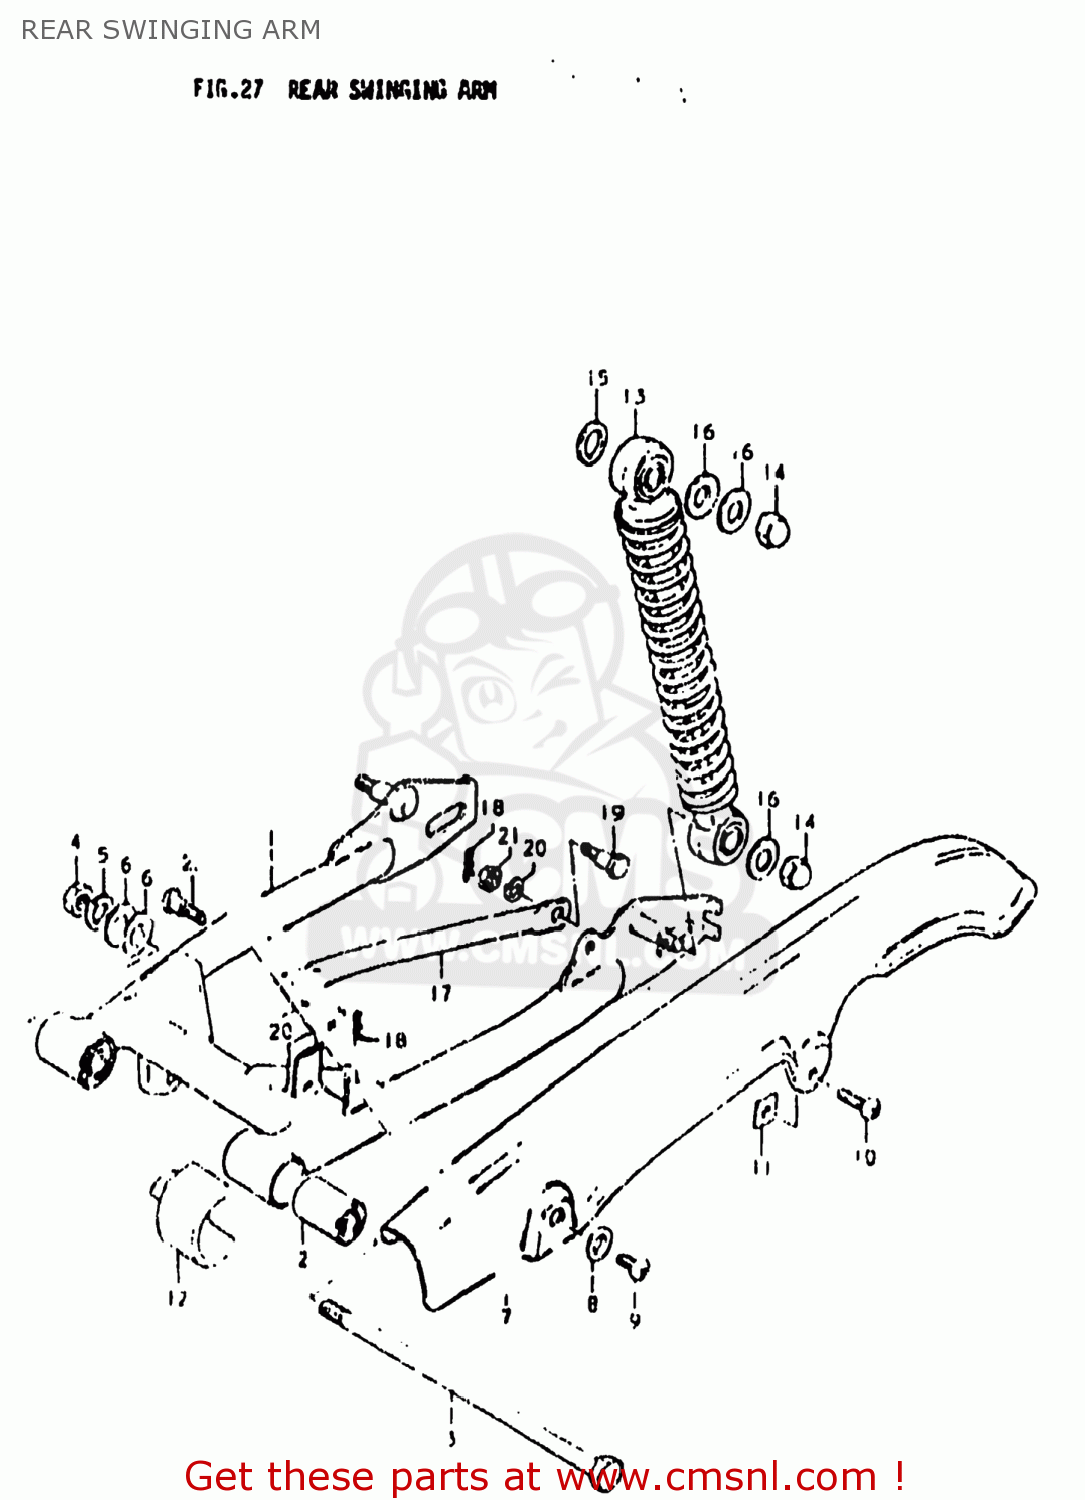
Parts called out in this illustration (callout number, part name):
1	SWING ARM ASSEMBLY,REAR
2	BUSH
3	SHAFT,REAR SWING ARM
4	NUT
5	LOCK WASHER
6	WASHER
7	CASE,CHAIN
8	WASHER
9	SCREW
10	SCREW 6X12
11	NUT,CHAIN CASE RR
12	BUFFER,CHAIN TOUCH DEFLECTOR
13	ABSORBER ASSEMBLY,REAR SHOCK
14	NUT, LOWER LH
15	WASHER
16	WASHER
17	TORQUE LINK,REAR
18	CLIP
19	BOLT(8X26.5)
20	LOCK WASHER
21	NUT
22	BOLT(8X22)
